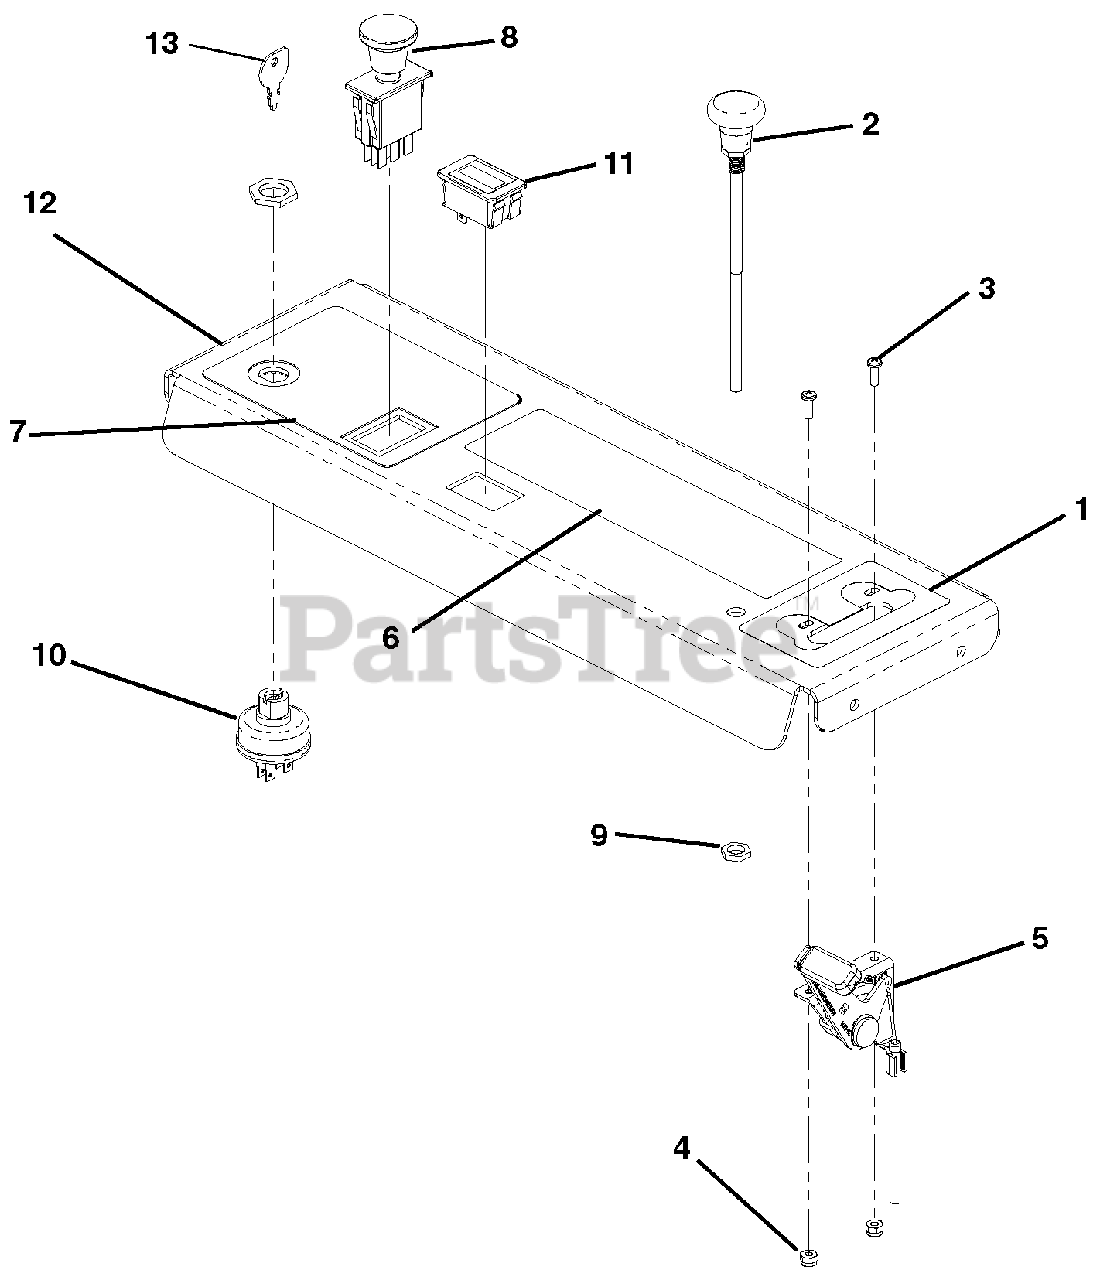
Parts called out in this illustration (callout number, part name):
1	Decal, Throttle
2	Cable, Choke
3	Screw, 8-32 x .5
4	Nut, Elastic Stop 8-32
5	Cable, Throttle
6	Decal, General Caution
7	Decal, PTO/Ignition
8	Switch, PTO Engagement
9	Nut, 3/8 UNF Hex Grade 5
10	Switch, Key - 3 Position
11	Hour Meter -Digital
12	Assembly, Control Panel w/Decals
13	Key, Ignition (Service Only)
